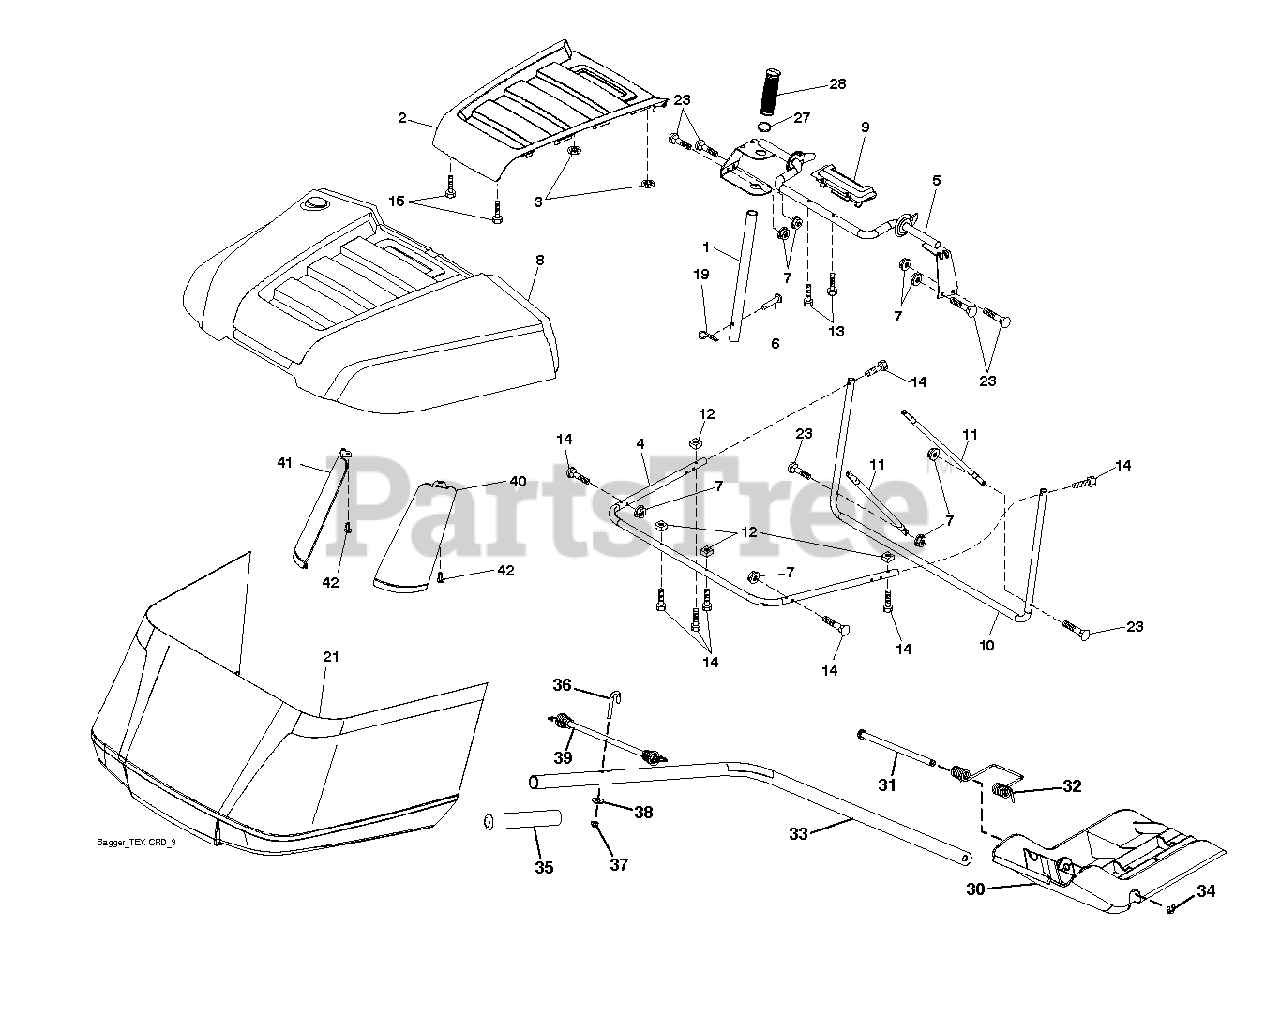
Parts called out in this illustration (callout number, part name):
1	TUBE.HANDLE.BAGGER.CRD/SRD.BLA
2	APPLIQUE.TOP.BAG.SRD.ORANGE
3	NUT.PUSH.156
4	SUBASM.TOP.TUBE.TEX.CRD
5	FRAME.ASM.TOP.BAGGER.SRD
6	RIVET,DRILLED
7	NUT T
8	BAGGER.TOP.SRD.APPLIQUE
9	INSERT.HANDLE.BAGGER.(2 2)
10	FRAME FRAME.FRONT.TEX.CRD
11	BRACE BRACE SIDE TUBE
12	NUT.SQUARE.1/4
13	SCREW.1/4X1.150.HXWSH
14	BOLT.SHOULDER.HX.WSH.1/4X1.150
15	SCREW,#8.FLAT.HEAD.DRILL.TIP
19	PIN.COTTER.5/16.BOW TI
21	BAG SUBASM. TEX CRD GEN 2 HUSQ
27	RB GROMMET.RUBBER.SRD
28	GRIP.HANDLE.BLACK
30	PLUG PLUG
31	PIN PIN.HINGE
32	SPRING SPRING DOUBLE TORSION
33	SHAFT SHAFT TEX CRD MULCH PLU
34	E-RING.5/16"
35	GRIP GRIP MULCH PLUG HAND
36	BOLT BOLT J
39	BUBGEE BUBGEE TEX CRD
42	CLIP CHRISTMAS TREE CLIP
